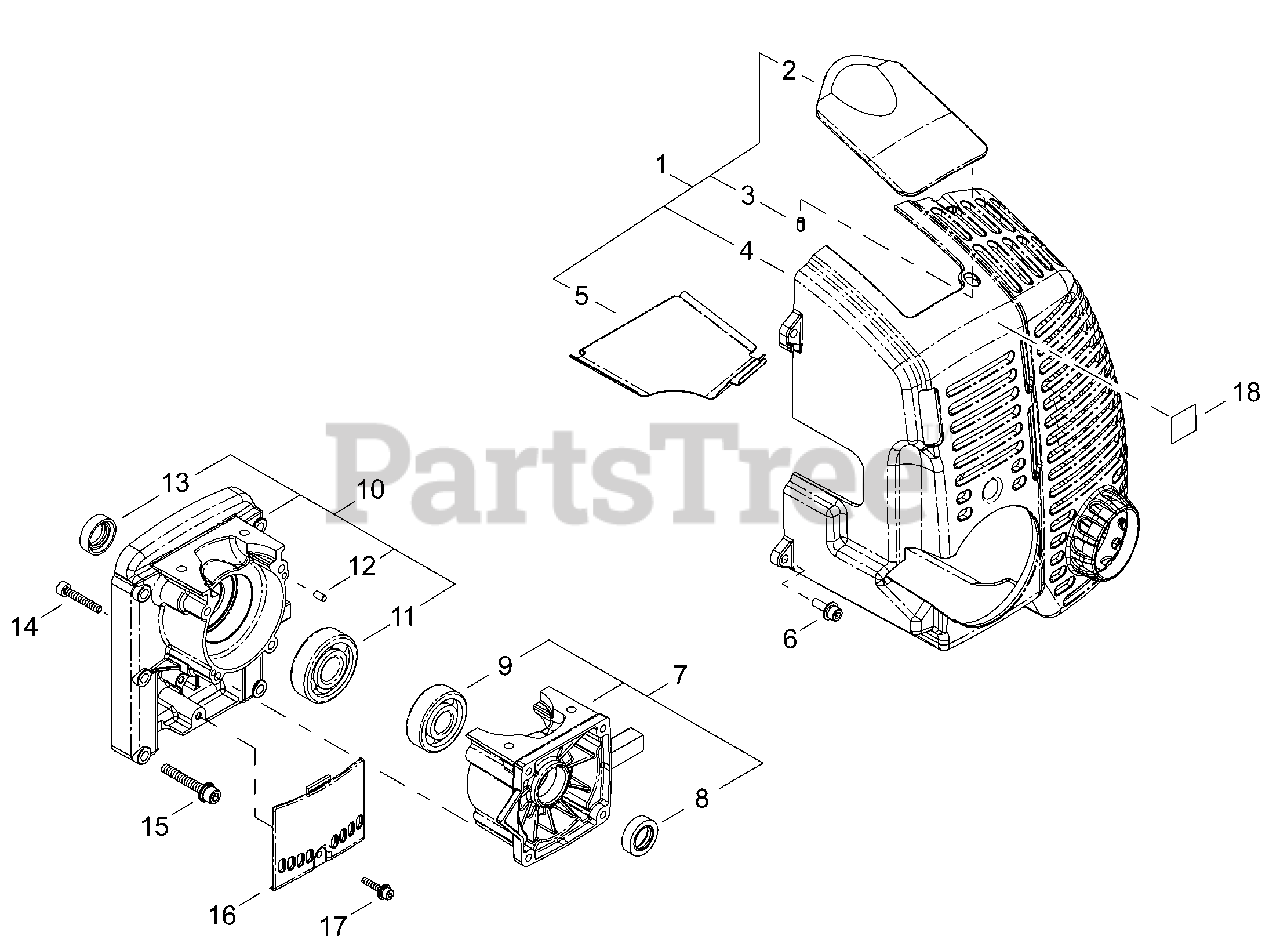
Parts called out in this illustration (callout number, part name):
1	ENGINE COVER ASSY
2	COVER, SPARK PLUG
3	PIN - 4X8
4	COVER, ENGINE
5	MUFFLER HEAT SHIELD
6	SCREW - 5X16
7	CRANKCASE ASSY - REAR
8	SEAL, OIL
9	BEARING, BALL - 6203C3
10	CRANKCASE ASSY - FRONT
11	BEARING, BALL - 6203C3
12	PIN - LOCATING
13	SEAL, OIL
14	SCREW - 5X30
15	SCREW - 6X40
16	IGNITION COIL COVER
17	SCREW - 4X20
18	LABEL - CAUTION
